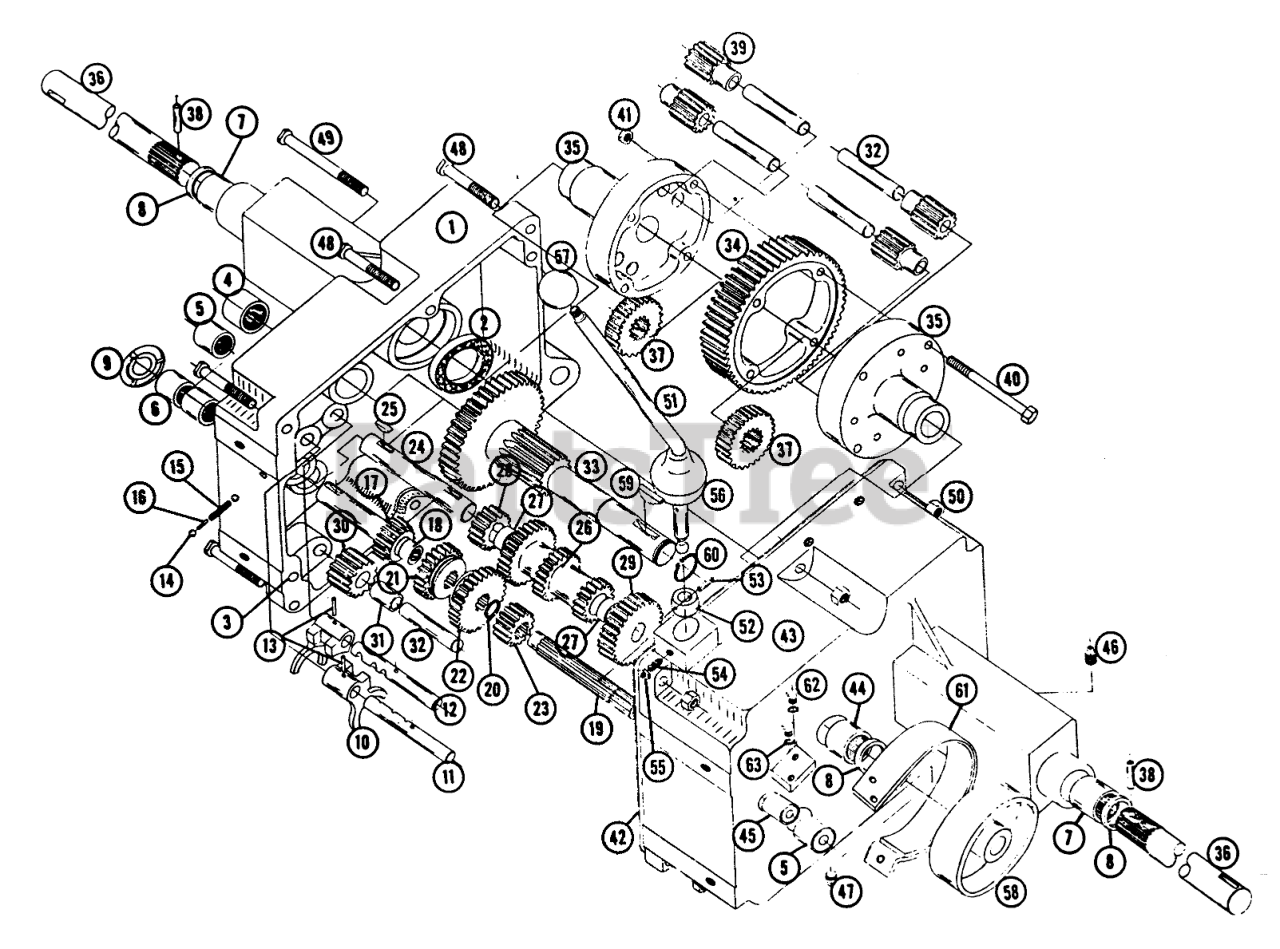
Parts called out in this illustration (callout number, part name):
3	PIN-DOWEL
4	BEARING-NEEDLE
5	BEARING-NEEDLE
7	BEARING-NEEDLE
10	FORK-SHIFT
13	PIN-ROLL
14	BALL-DETENT
18	BEARING-NEEDLE
20	Snap Ring 3/4 I.D.
23	GEAR
25	Key
27	BUSHING-BRONZE
29	GEAR-CLUSTER SHAFT
30	GEAR/BUSHING ASM-REVERSE IDLER
31	BUSHING
32	PIN-DIFFERENTIAL
34	SVC BULLT 394
35	DIFFERENTIAL CASE
37	AXLE GEAR
42	GASKET-TRANSMISSION
46	Plug 1/4 Pipe
47	Plug 3/8 Pipe
48	Bolt, 3/8 16 x 2
49	Bolt Hex 3/8-16 x 1
51	Stick-Shift
53	Roll Pin
54	Screw Soc. Hd.-Set 1/4-20 x 3/4
55	Nut 1/4-20
56	COVER-DUST
59	KEY-WOODRUFF
60	Snap Ring 1" Shaft
62	Bolt-1/4-20 x 5/8
63	Lockwasher
